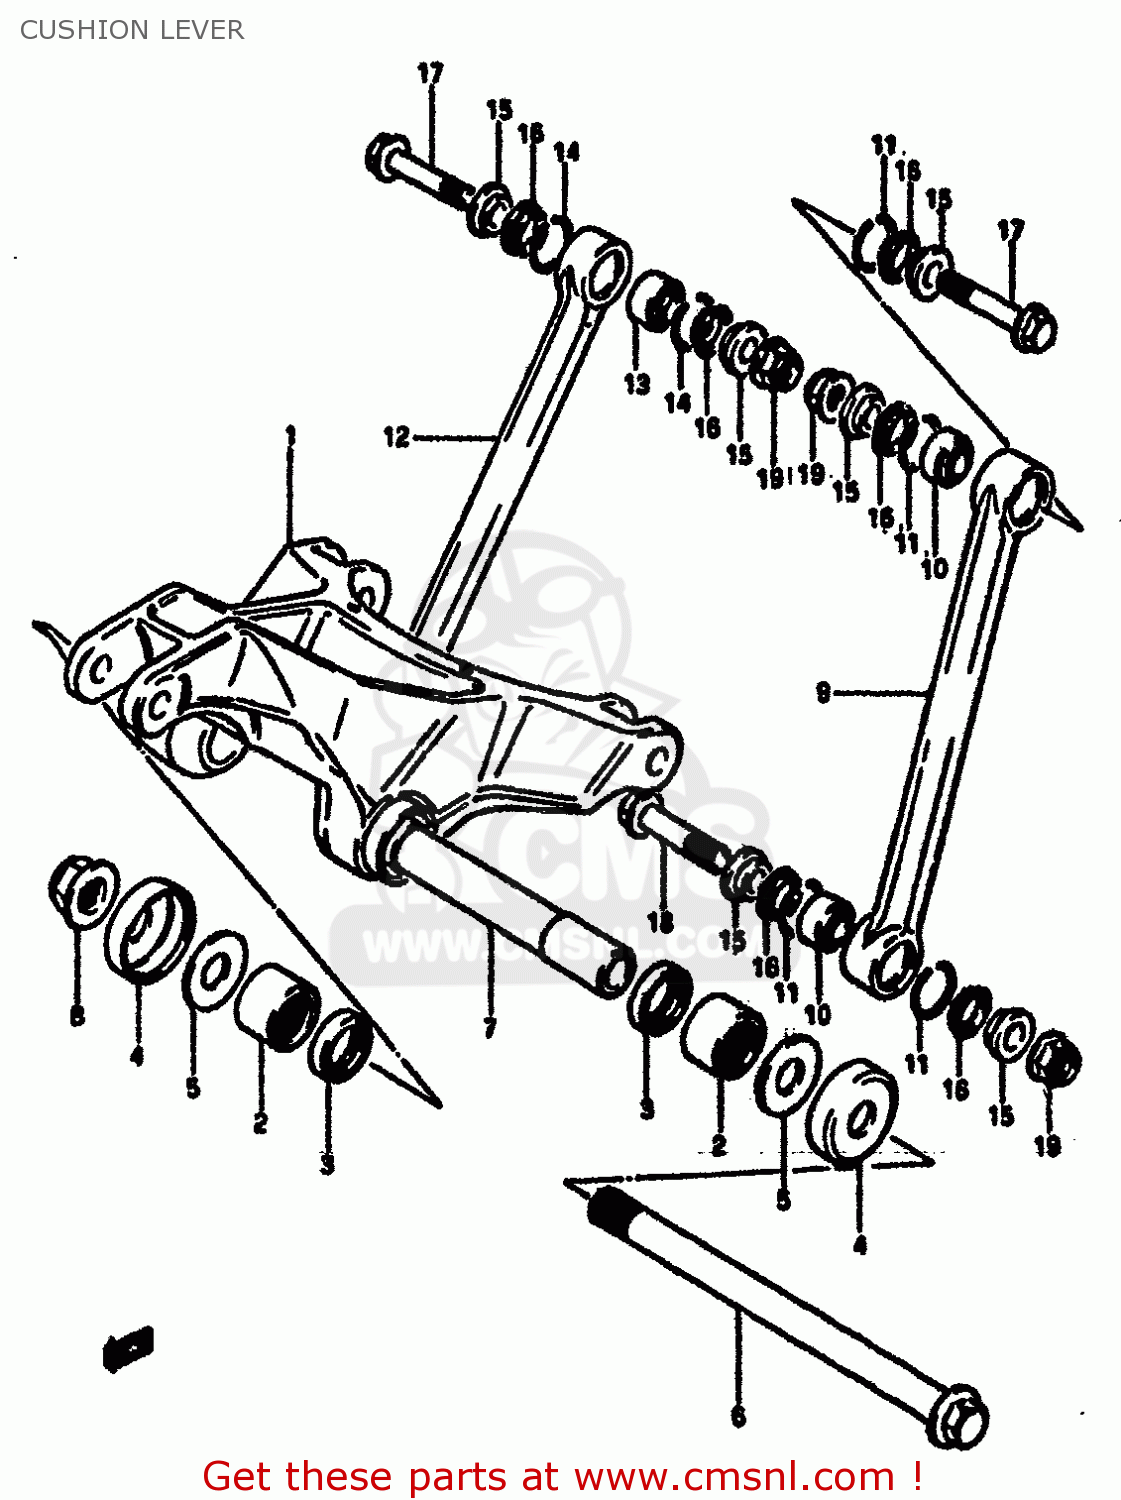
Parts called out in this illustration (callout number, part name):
1	LEVER SET,REAR CUSHION
2	BEARING(20X27X25)
3	SEAL,CUSHION LEVER DUST
4	CVR,RR SWGARM DUST SEAL(OD:40)
5	WASHER
6	SHAFT,REAR CUSHION LEVER
7	SPACER,REAR CUSHION LEVER
8	NUT
9	ROD SET,REAR CUSHION,LEFT
10	BEARING(10X21X13)
11	RING,BEARING STOPPER
12	ROD SET,REAR CUSHION,RIGHT
13	BEARING(10X21X13)
14	RING,BEARING STOPPER
15	SPACER,REAR CUSHION ROD
16	DUST SEAL,RR CUSHION ROD
17	BOLT,RR CUSHION ROD UPR
18	BOLT,RR CUSHION ROD LWR
19	NUT
